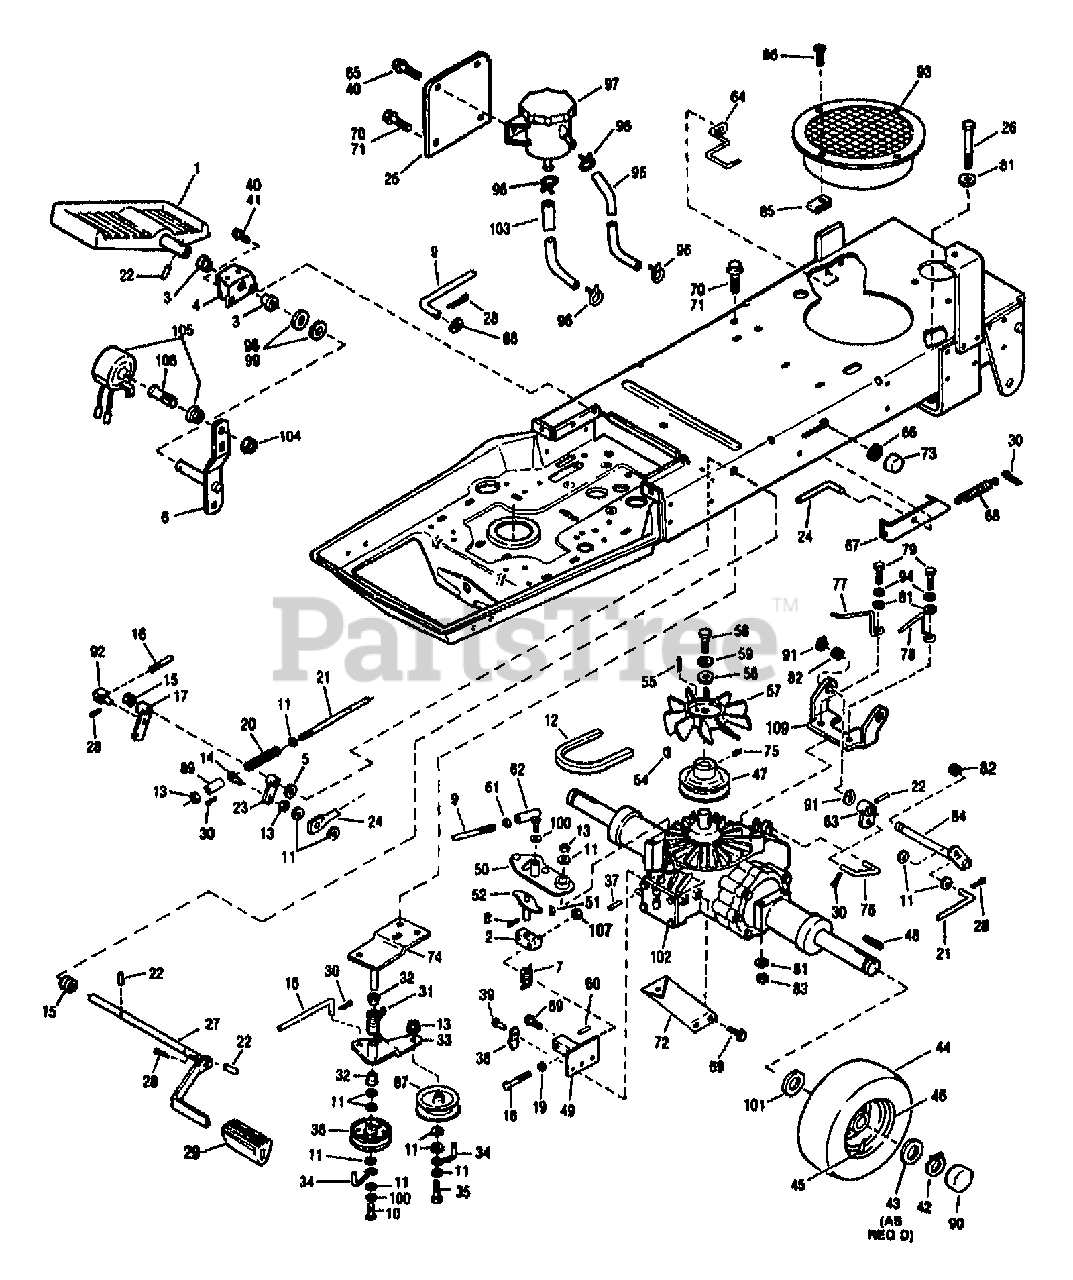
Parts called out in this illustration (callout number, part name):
2	BLOCK-PIVOT
3	BEARING-FLANGE
4	SUPT-HYD PEDAL
5	WASHER-1.305X.649X.098 ZP
6	ASSM-CONT {13065/13066}
6	ASSM-CONTROL ARM {13064}
7	SPRING-TORSION
8	PIN-ROLL .188X.75
9	ROD-SPEED CONTROL
9	ASSM-CONTROL ARM {13064}
10	SCR-HH 3/8-16X2.25 G5 ZP
11	WASHER-FLAT 3/8 SAE
13	NUT-LOCK 3/8-16
15	BUSHING-.68X.62X.15 FLNG
16	ROD-CLUTCH
17	ASSM-ARM
19	NUT-JAM
20	SPRING-COMP.
21	LINK-BRAKE
22	PIN-ROLL .188X1.0
23	ASSM-ARM
24	ROD-BRAKE LOCK
25	SUPPORT-TANK
26	SCR-HH 5/16-18X3.0
27	ASSM-BRAKE PEDAL
28	PIN-COTTER .120X1.00 ZP
29	FOOT REST
30	PIN-COTTER .125X.50
31	SPRING-TORSION
32	BUSHING-.5X.5 NYLON FLNG
33	ASSM-IDLER ARM
34	GUIDE-BELT
35	SCR-HH 3/8-16X1.75 G5 ZP
36	LATCH
37	PIN-DRIVE .25X3.0 ZP
39	RIVET-POP
40	SCR-HH 1/4-20X.625
41	NUT-HF/LK 1/4-20 ZP
42	RING-HEAVY EXT HD 1.0 ID
43	WASHER-1.88X1.015X.06 ZP
44	TIRE-REAR
45	STEM-VALVE
46	WHEEL-DISC
47	SHEAVE-HYDRO
48	KEY-.25 SQ X 1.5
49	ASSM-ADJUSTOR BLOCK
50	ASSM-SPEED CONT ARM
51	KEY-WOODRUFF .125X.5
52	ASSM-PIVOT SHAFT
54	KEY-WOODRUFF
55	PIN-ROLL .188X.75
56	WASHER-.865X.281X.1793
57	FAN-HYDRO TRANSMISSION
58	SCR-HH 1/4-20X1.0
59	WASHER-LK .25 ZP
60	PIN-DOWEL .375 X 2.51
61	NUT-HEX/JAM 3/8-24 ZP
62	JOINT-BALL
63	ASSM-BRAKE ARM
64	GUIDE
65	NUT-HT LK 1/4-20
66	WASHER-FLAT
67	BRKT-INTERLOCK {13065/13066}
67	BRACKET-INTERLOCK {13064}
68	SPRING
69	SCR-HFLK 5/16-18X.50 ZP
70	SCR-LOCK
71	NUT-HFLK 5/16-18 ZP
72	BRACE-TRANSAXLE
73	CAP-PUSH ON
74	ASSM-LEVER SUPP
75	SCR-SET 1/4-28X.38 HXSKT
76	LINK-BRAKE
77	GUIDE-BELT
79	SCR-HH 5/16-18X1.0 G5 ZP
81	WASHER-FLAT 5/16 SAE
82	BEARING-FLANGED
83	NUT-TOP/LK 5/16-18 ZP
84	ASSM-JACKSHAFT
87	PULLEY-IDLER
90	CAP-WHEEL
91	RING-RETAINING
92	PIVOT
93	SHROUD-FAN
94	WASHER-LK .312 ZP
95	HOSE-FUEL 18"
96	CLAMP-HOSE
97	ASSM-OIL RESERVOIR
99	WASHER-1.0X.64X.09
100	WASHER-LK .375 @ DEPL
101	SHIM-1.25X1.01X.06
102	TRANS-HYDRO
104	NUT-WHIZ LOCK {NOT 13064}
105	ASSM-MAGNET {NOT 13064}
106	SCR-SPECIAL {NOT 13064}
107	NUT-HEX/JAM 3/8-24
109	SUPPORT-SHAFT
